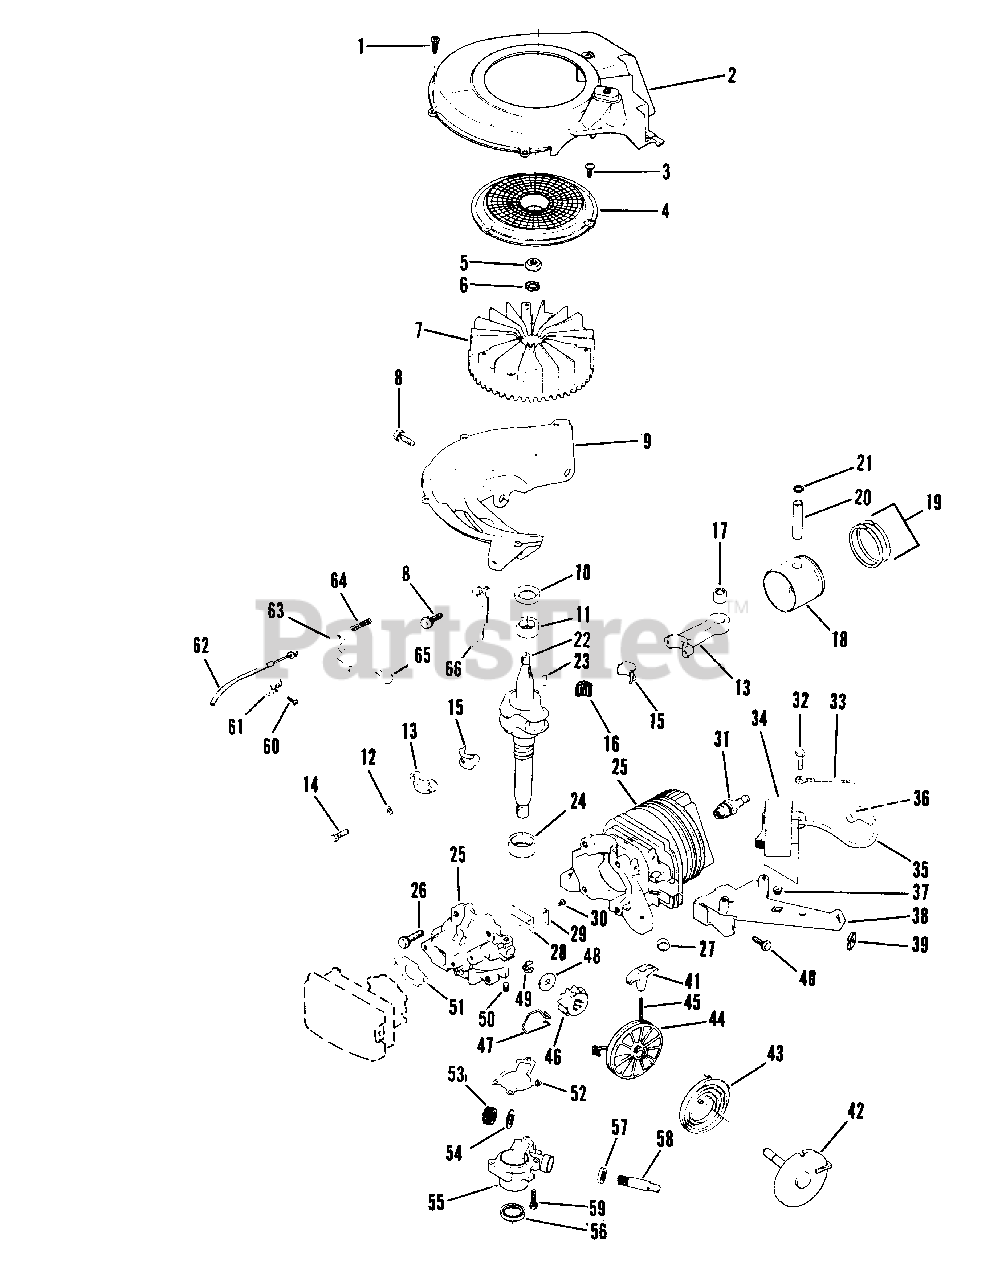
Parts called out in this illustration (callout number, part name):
1	Screw
2	Air Baffle & Eyelet Assembly
3	Screw-Flywheel Screen
4	Screen-Flywheel
5	Nut-Flywheel
6	Lockwasher
7	Flywheel Assembly
8	Screw
9	Base-Shroud
10	Oil Seal-Upper
11	Bearing-Upper
12	Lockplate
13	Connecting Rod Assembly
14	Screw
15	Liner-Split
16	Needle Bearing Set
17	Bearing Assembly
18	Piston & Ring Set
19	Ring Set
20	Wrist Pin
21	Retaining Ring
22	Crankshaft
23	Key-Flywheel
24	Bearing-Lower
25	Cylinder & Crankcase Cover Assembly
26	Screw-Cover to Crankcase
27	Plug
28	Reed
29	Plate-Reed Hold Down
30	Screw-Reed to Crankcase Cover
31	Spark Plug
32	Screw-C.D. Mounting
33	Lead Assembly-Ignition
34	C.D. Ignition Module & Lead Assembly
35	High Tension Lead
36	Spring Terminal
37	Grommet-C.D. Bracket
38	Bracket-C.D. Mounting
39	Clip-"U"
40	Screw
41	Handle-Starter
42	Cup & Pin Assembly
43	Spring
44	Pulley
45	Rope
46	Pinion
47	Spring-Drag
48	Washer
49	Retainer
50	Set Screw-Starter Assembly
51	Gasket-Carburetor to Crankcase Cover
52	Gasket-Gear Box
53	Gear
54	Washer-Thrust
55	Gear Box Assembly
56	Oil Seal-Crankshaft
57	Seal-Driveshaft
58	Driveshaft
59	Screw-Gear Box
60	Screw-Clip-Cable Casing
61	Clip
62	Cable-Interlock
63	Lever-Lockout
64	Spring-Interlock
65	Bolt-Shoulder
66	Bracket-Cable
